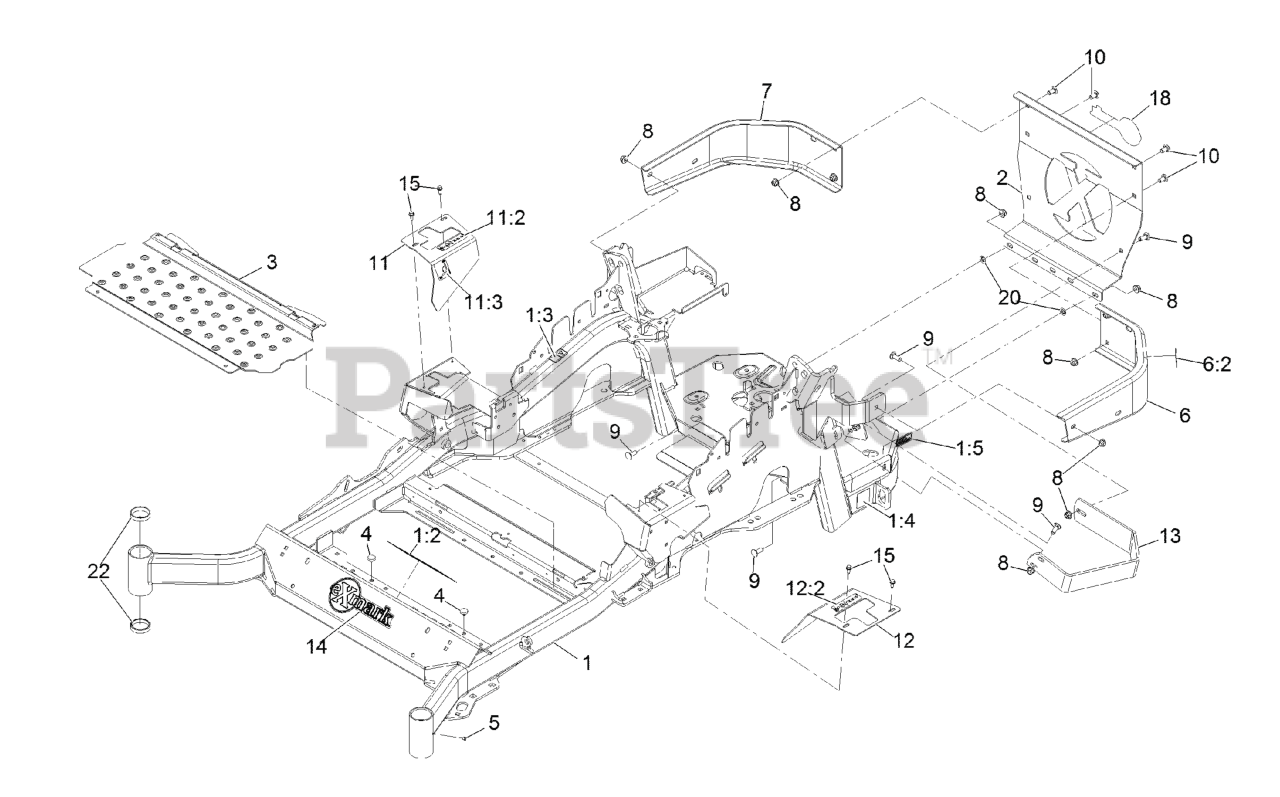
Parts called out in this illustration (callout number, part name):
1	MAINFRAME ASM
1:2	DECAL-DANGER
1:3	DECAL-WARNING
1:4	DECAL-HAZARD, PINCHED FINGER
1:5	DECAL-SPARK ARRESTER
2	PLATE,REAR GUARD
6	LH BUMPER ASM
6:2	DECAL-WARNING
7	BUMPER-RH
8	NUT-HF, NI
9	SCREW-CARR
10	SCREW-CARR
11	RH MOTION CONTROL COVER ASM
11:2	DECAL-CONTROL, MOTION
11:3	DECAL-PARK BRAKE, CE
12	LH MOTION CONTROL COVER ASM
12:2	DECAL-CONTROL, MOTION
13	GUARD-MUFFLER
14	DECAL-EXMARK LOGO
15	SCREW-HWH
18	DECAL-EXMARK LOGO
19	Decal-Patent Ttco.Com
20	NUT-PUSH
21	DECAL-FUEL FILL, CE
22	CUP-BEARING
